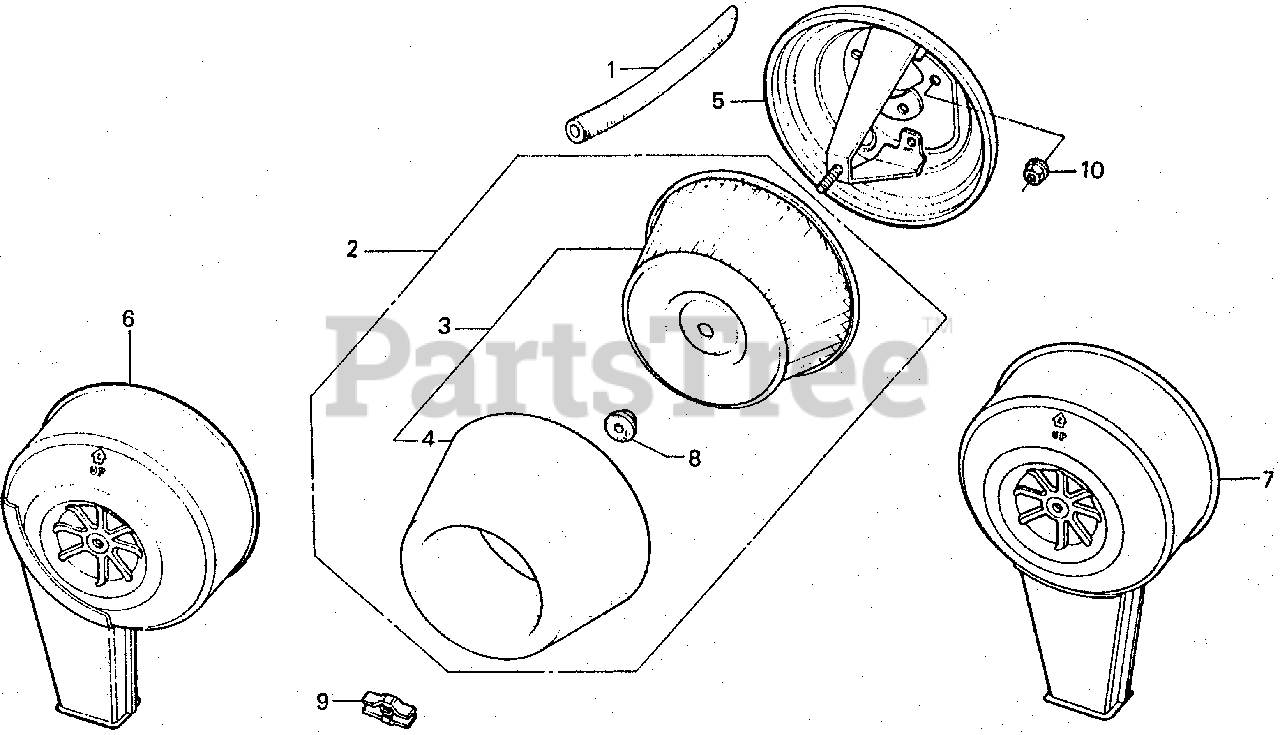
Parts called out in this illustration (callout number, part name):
1	TUBE, BREATHER
3	ELEMENT, AIR CLEANER
5	HOUSING, AIR CLEANER
5	HOUSING, AIR CLEANER (NOT AVAILABLE)
6	COVER, AIR CLEANER
7	COVER, AIR CLEANER
8	GROMMET, AIR CLEANER
9	NUT, AIR CLEANER COVER (DACRO COATING)
10	NUT, FLANGE (6MM)
